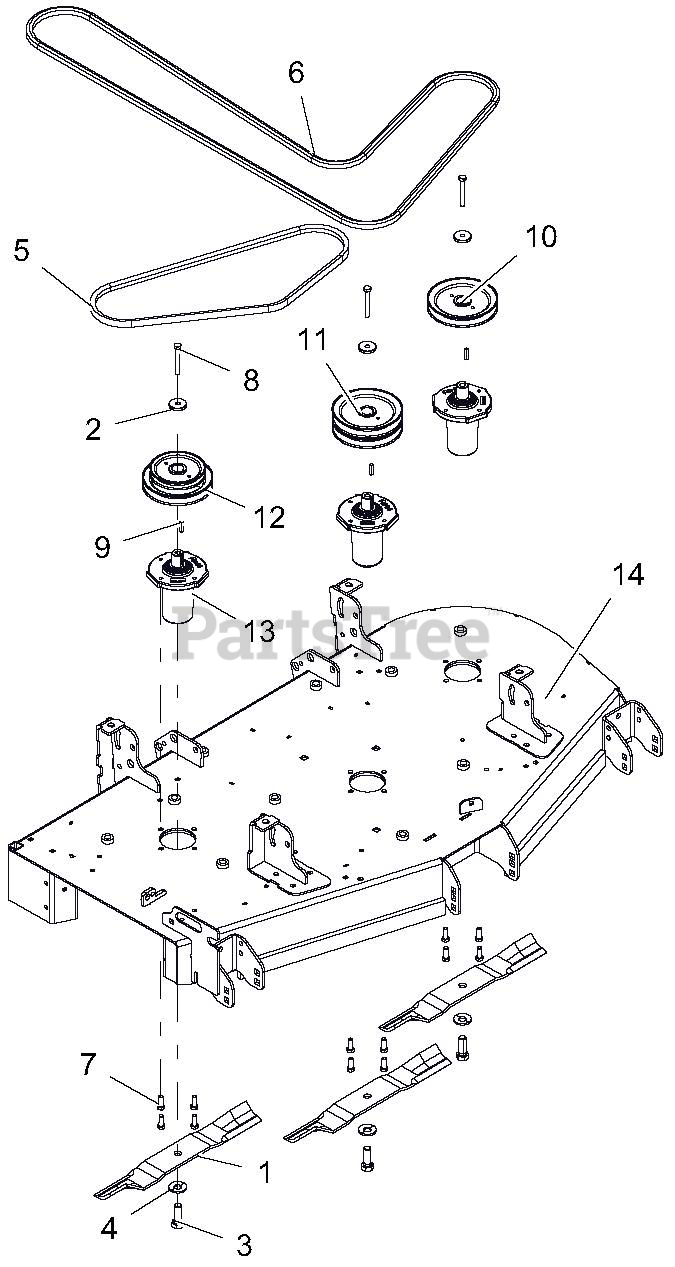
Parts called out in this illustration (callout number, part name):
1	BLADE, 18.00" MOVER (HI-LIFT)
2	RETAINER, SHEAVE SPINDLE
3	BLT, HEX .62-18X1.75 GR8 YWZC
4	WSHR, BLVL .63X1.625X.14
5	BELT, B 56.00 RAW COGGED
6	BELT, BB 118.00 WRAPPED HEX
7	BLT-HEX .38-16X1.00 GR5 YWZC EP30
8	BLT-HEX .38-16X2.75 GR8 YWZC
9	KEY-SQ .250X.250X1.00 RC 40-50
10	PULLEY, SINGLE -1" ID X 6.00" OD-BLACK
11	PULLEY, DOUBLE -1" ID X 6.00" OD-BLACK
12	PULLEY, DOUBLE -1" ID X 6.00" & 4.75" OD
13	SERVICE, ASM SPINDLE- DUCTILE
14	WLDMT, 52" PT100 SIDE DISCH DECK
